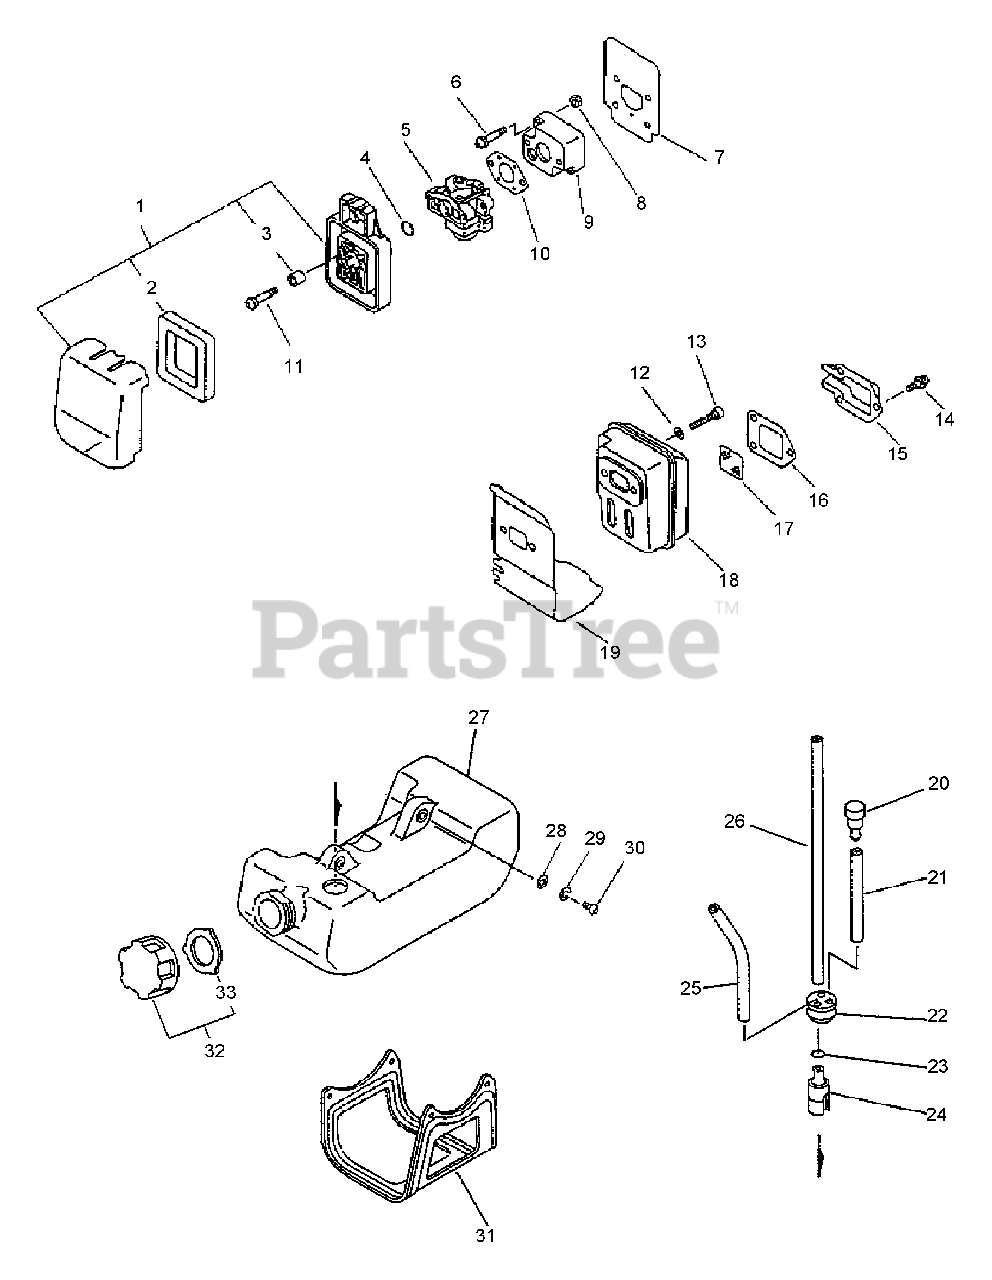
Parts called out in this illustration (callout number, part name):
1	AIR CLEANER ASSY
2	FILTER, AIR
3	SLEEVE
4	O-RING - 15
5	CARBURETOR WYL-1
5	CARBURETOR WYL-23
6	SCREW - 5X20
7	SHIELD, INTAKE
9	INSULATOR, INTAKE
10	GASKET, INTAKE
11	SCREW - 5X64
12	WASHER - 5
13	SCREW - 5X55
14	SCREW - 4X10
15	GUIDE, EXHAUST - OUTER
16	GASKET, EXHAUST
17	SCREEN, SPARK ARRESTOR
18	MUFFLER
19	GASKET, EXHAUST
20	VENT, FUEL TANK
21	PIPE - 3X5X30 -- BLACK
22	GROMMET
23	CLIP - 6
24	FILTER, FUEL
25	PIPE - 3X6X80 -- CLEAR
26	PIPE - 3X5X160 -- BLACK
27	FUEL TANK ASSY
28	WASHER - 5
29	LOCKWASHER - 5
30	SCREW - 5X16
31	GUARD, FUEL TANK
32	CAP ASSY
33	GASKET, CAP
